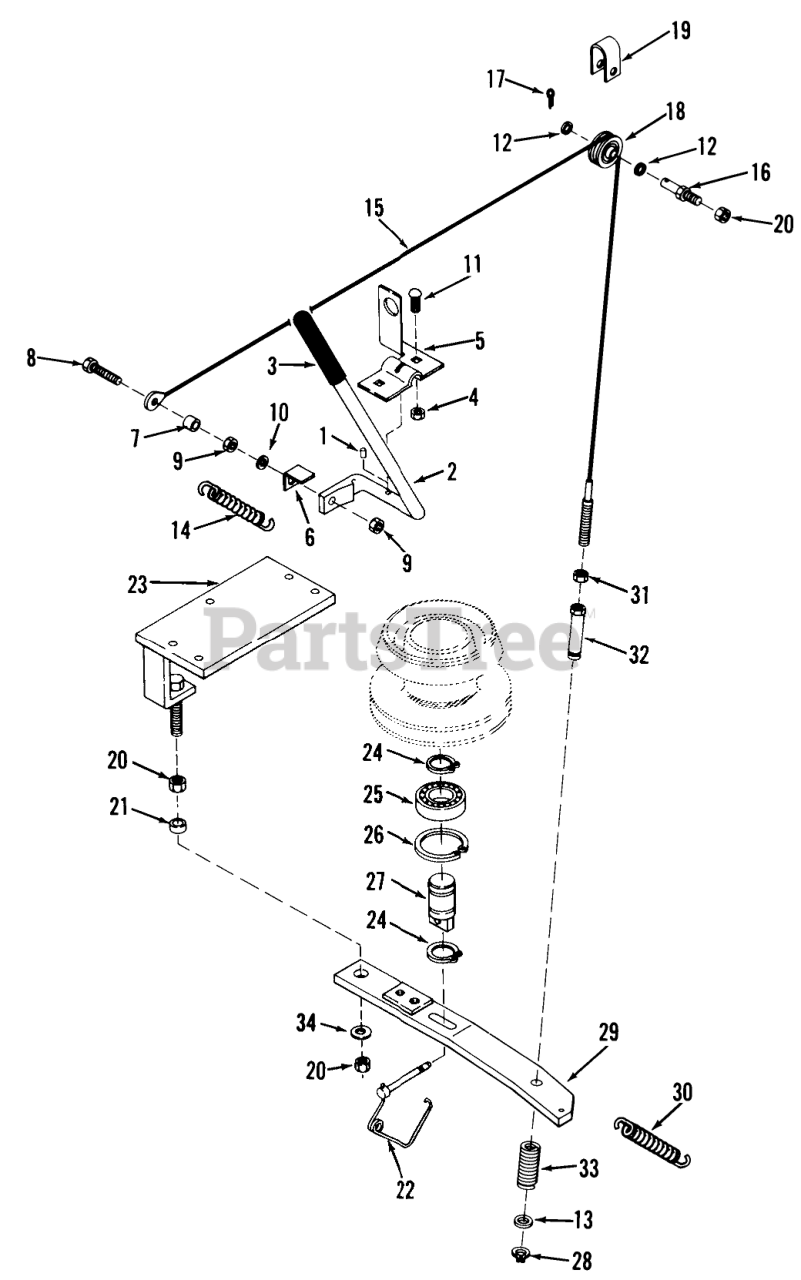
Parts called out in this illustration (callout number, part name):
1	SPIROL PIN
3	GRIP
13	Washer
14	SPRING-EXTENSION
19	STRAP-CABLE
21	SPACER-CLUTCH BAR
27	SHAFT-CLUTCH HSG
33	SPRING-CLUTCH
